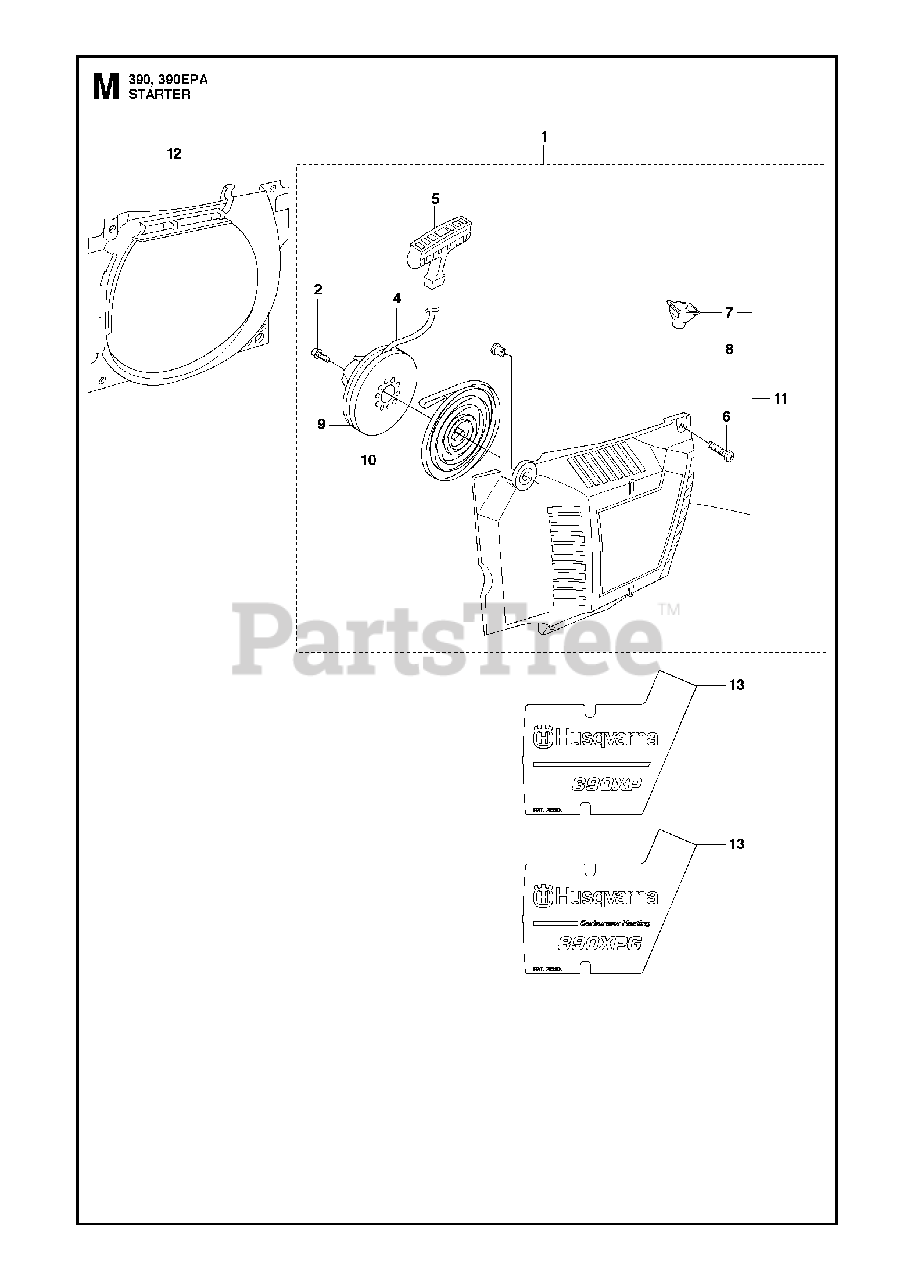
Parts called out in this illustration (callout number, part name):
1	STARTER DEVICE CPL
2	SCREW
4	STARTER CORD
5	STARTER HANDLE
6	SCREW
7	SLEEVE
8	BUSHING
9	STARTER PULLEY
10	SPRING
11	STARTER HOUSING
12	AIR CONDUCTOR
13	LABEL 390XPG
